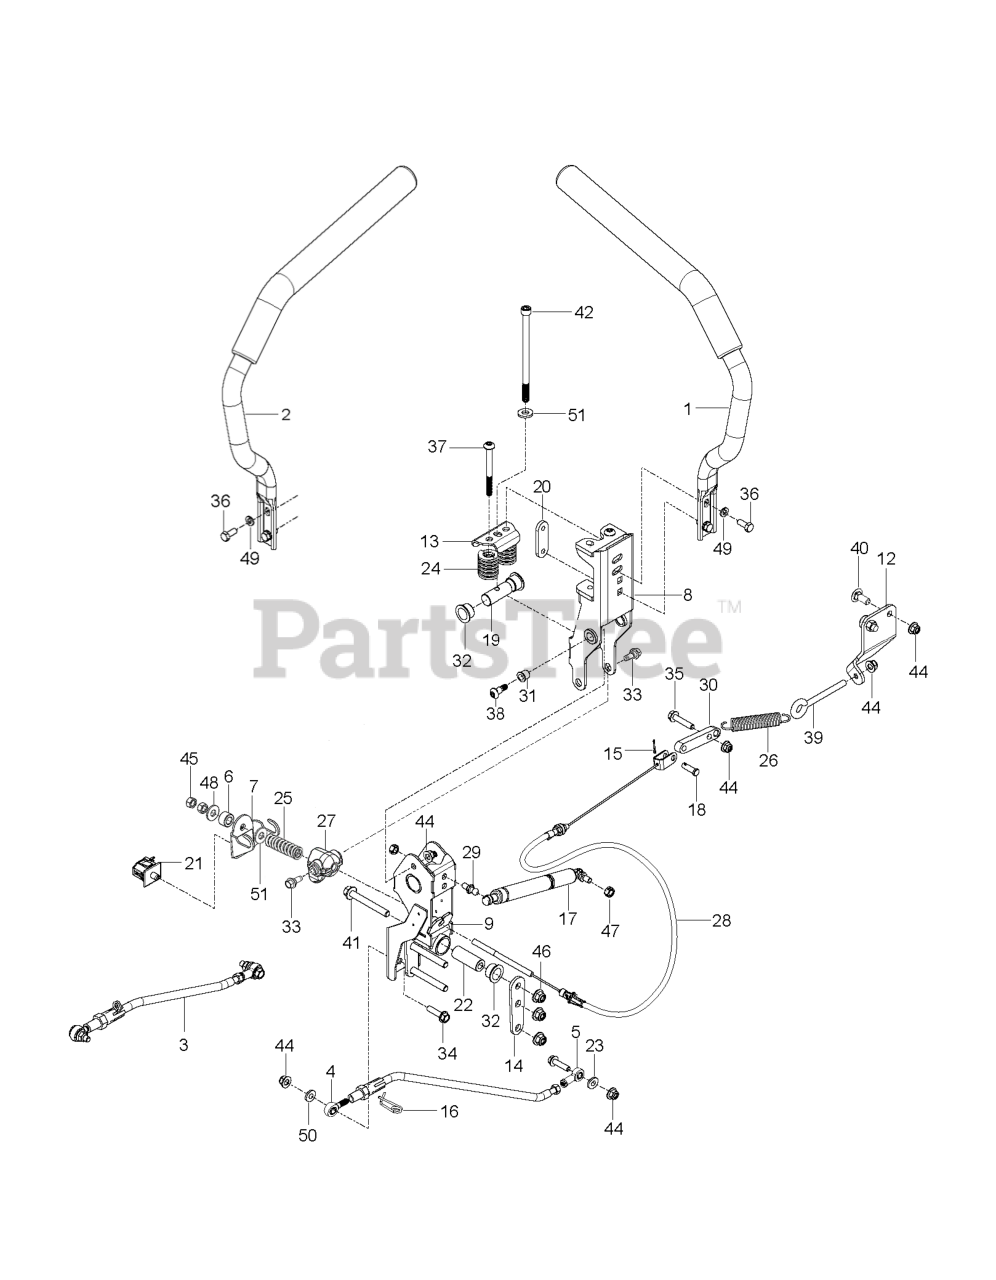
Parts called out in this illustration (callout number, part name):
1	LEVER.ASM.DRIVE.LH
2	LEVER.ASM.DRIVE.RH
3	Rods
3	CONTROL ROD COUPLER KIT
4	ROD.END.MALE.LH.THREAD
5	JOINT.HEIM.FEML.5/16.RH.THREAD
8	KIT.CARRIER.UPPR.W/BUSHINGS.RT
8	KIT.CARRIER.UPPR.W/BUSHINGS.LT
9	KIT.CARRIER.LWR.W/BUSHINGS
12	BRACKET.PNT.RETRN.SPRNG.LH.BLK
12	BRACKET.PNT.RETRN.SPRNG.RH.BLK
14	BRACKET.PNT.CONTROLS.MTG.EDIP
15	PIN COTTER;LOCKING;BOWTIE;1IN
16	CLIP.RETAINER.CONTROLS
18	PIN.CLEVIS.5/16.DIA.3/4.USABLE
22	SPACER.PIVOT
23	SPACER.7_16OD;5_16ID;STEP.UP
24	SPRING 1.25"ODX1.5"L
25	SPRING, BRAKE ROD
28	CABLE.BRAKE.PARK
29	STUD.BALL.10MM
31	BEARING.FLG.3/8.SHAFT.1/2.HSG
32	BEARING, FLANGE
33	SHOULDER BOLT 5/16-18TT
34	HHFS 5/16-18 X 1.25 TPBLT GD 5
36	HCS 5/16C X 3/4
38	SCREW.SHLDR.3/8 X 1/2.5/16-18
39	GSPW Bolts
41	HHFS 3/8-16 X 3 GRD 5 ZD
44	NUT HEXAGON FLANGE 5/16-18 ST
47	NUT 5/16C CENTERLOCK
49	WASHER.LOCK.HVY.HLCL.SPR.5/16
50	WASHER 11/32 X 11/16 X 14 GA T
51	WASHER, 3/8 THICK
